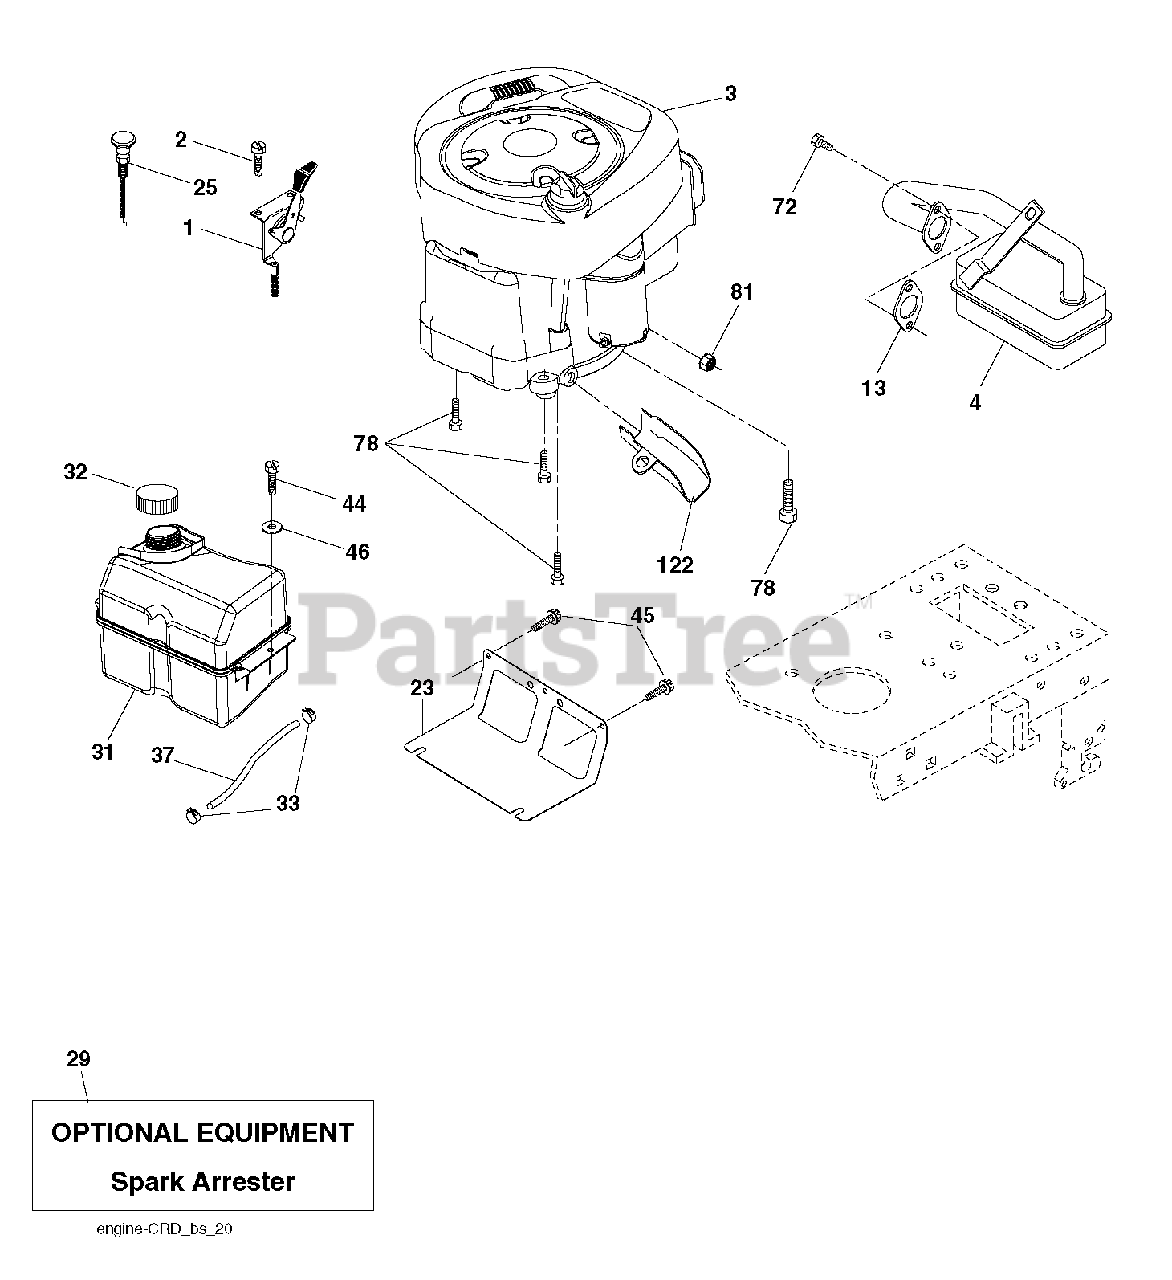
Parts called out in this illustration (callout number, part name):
1	CONTROL.THROTTLE/CHOKE.BLACK
2	SCREW
4	MUFFLER.LT.BRIGGS.14HP.IC/OHV
13	REPL BY 532 27 22-93
23	SHIELD.BROWNING.DBR.GUARD
25	KNOB.ERGO.EXTENDED.RED (1 2)
29	KIT.SPARK ARRESTOR 794945 B&S
31	TANK.FUEL.FRT.N/CAP.2.0GAL.DAP
32	CAP ASM.FUEL.2.25"FR.
33	HOSE CLAMP
37	LINE.FUEL.20
44	SCREW HEXWSHR 1/4-20X3/4
45	SCREW, 3/8-16X3/4
46	WASHER
72	SCREW.SOCKET HD.5/16-1
78	SCREW.3/8-16
81	NUT
122	EXTENSION DRAIN OIL
